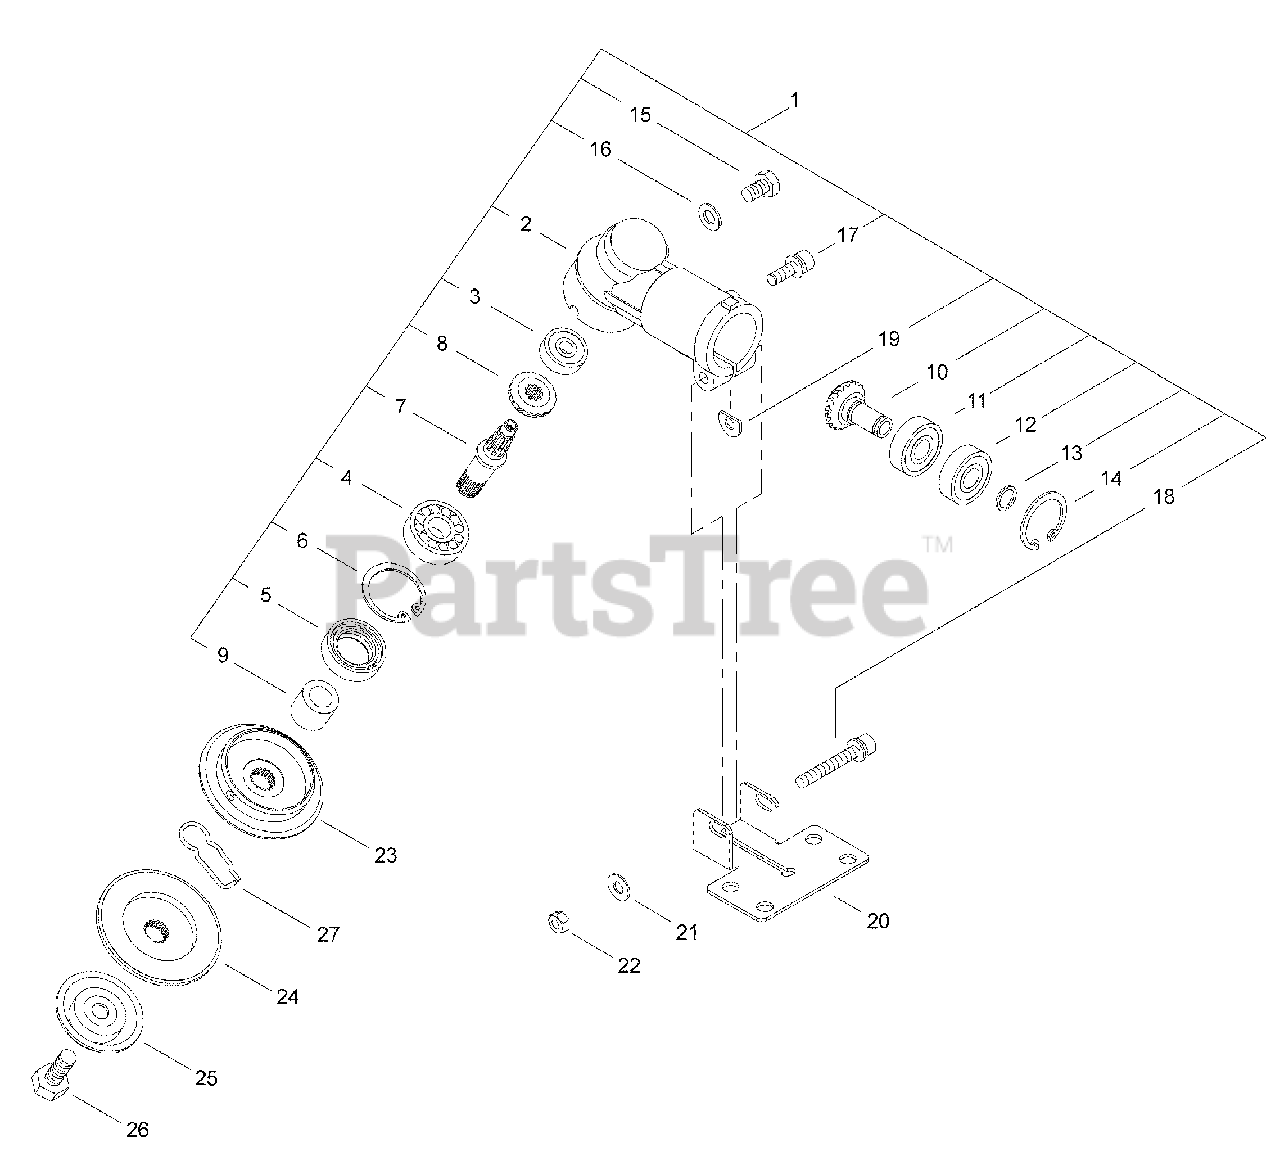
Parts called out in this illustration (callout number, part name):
1	GEAR CASE ASSY
2	CASE, GEAR
3	BEARING, BALL - 609
4	BEARING, BALL - 6201
5	SEAL, OIL
6	RING, RETAINING - 32
7	GEAR - SHAFT
8	GEAR - BEVEL
9	COLLAR
10	PINION SET
11	BEARING, BALL - 6901
12	BEARING, BALL - 6901ZZ
13	RING, RETAINING
14	RING, RETAINING - 24
15	BOLT - 6X10
16	WASHER
17	SCREW - 5X16
18	SCREW - 6X40
19	SHIM
20	BRACKET
21	WASHER - 6
22	NUT - 6
23	HOLDER - A
24	HOLDER
25	GUARD
26	BOLT - 8 -- LEFT HAND
27	CLIP
